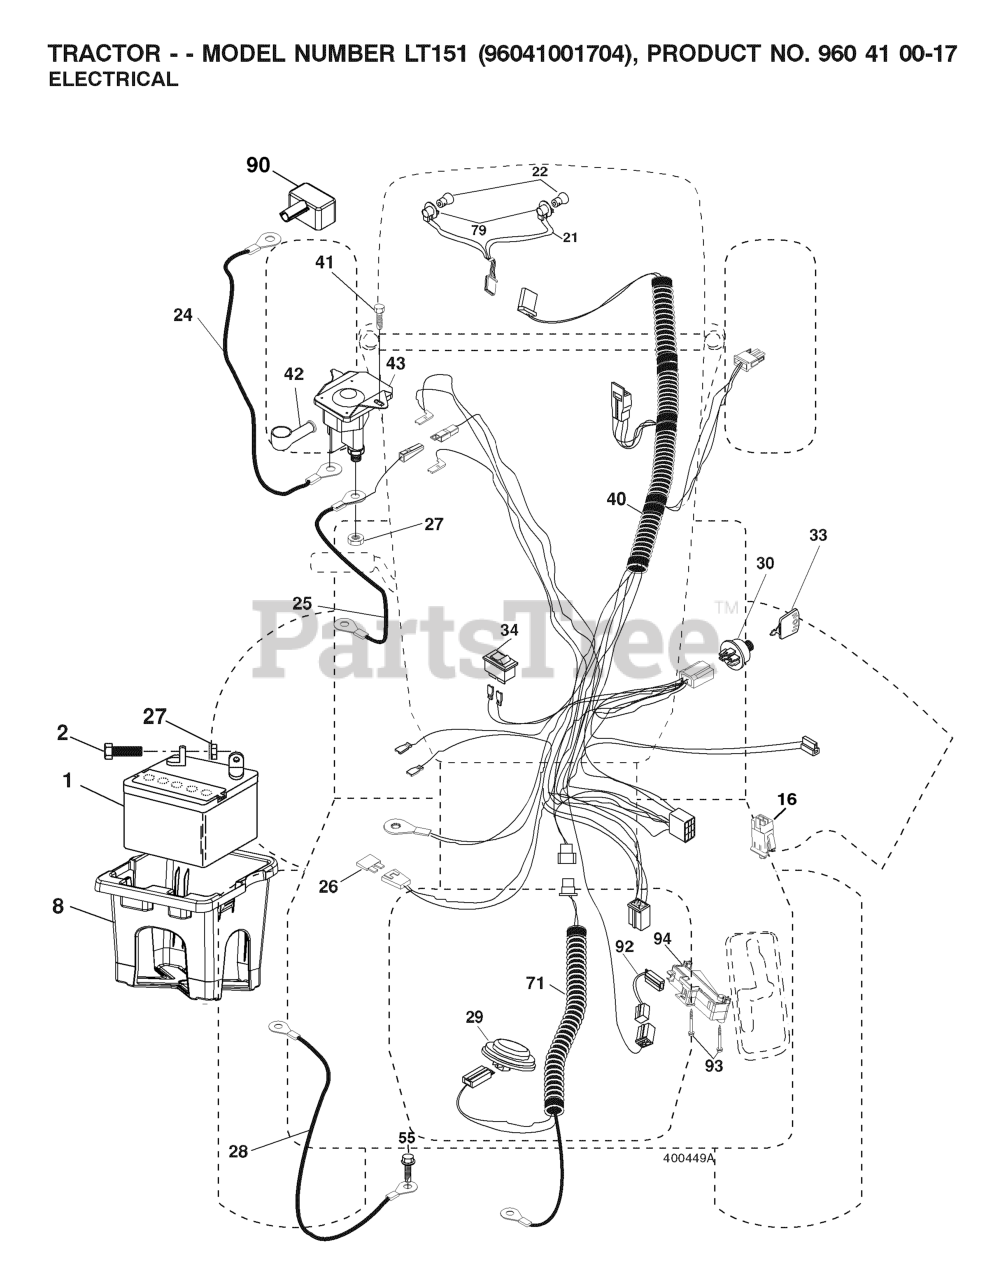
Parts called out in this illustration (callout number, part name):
1	BATTERY 12V .35 AMP
2	BOLT.HEX.1/4.X.3/4.DICHROMATE
8	BOX.BATTERY.MNT.REAR.L
16	SWITCH INTERLOOK PUSH-IN
21	HARNESS.LIGHT W/4152J BULBS
25	CABLE.STARTER.6GA.RED.
26	FUSE 20AMP
27	NUT
28	CABLE.BLACK.18"REAR.BA
29	SWITCH.SEAT.DELTA.OPC.
30	SWITCH.IGN.DELTA.W.LGH.ROS
33	KEY MLD GEN DELTA
40	HARNESS IGN. DASH
41	SCREW
42	TERMINAL COVER
43	SOLENOID.W/BRASS.PLUNGER
55	SCREW 5/16"
71	HARNESS.IGN.CHASS.TEX.REAR.BAT
79	BULB HOLDER ASM.
90	COVER, TERMINAL BATTERY
92	HARNESS.PIGTAIL.CONSLE
93	SCREW.PLASTITE
94	MODULE.REVERSE.ROS
